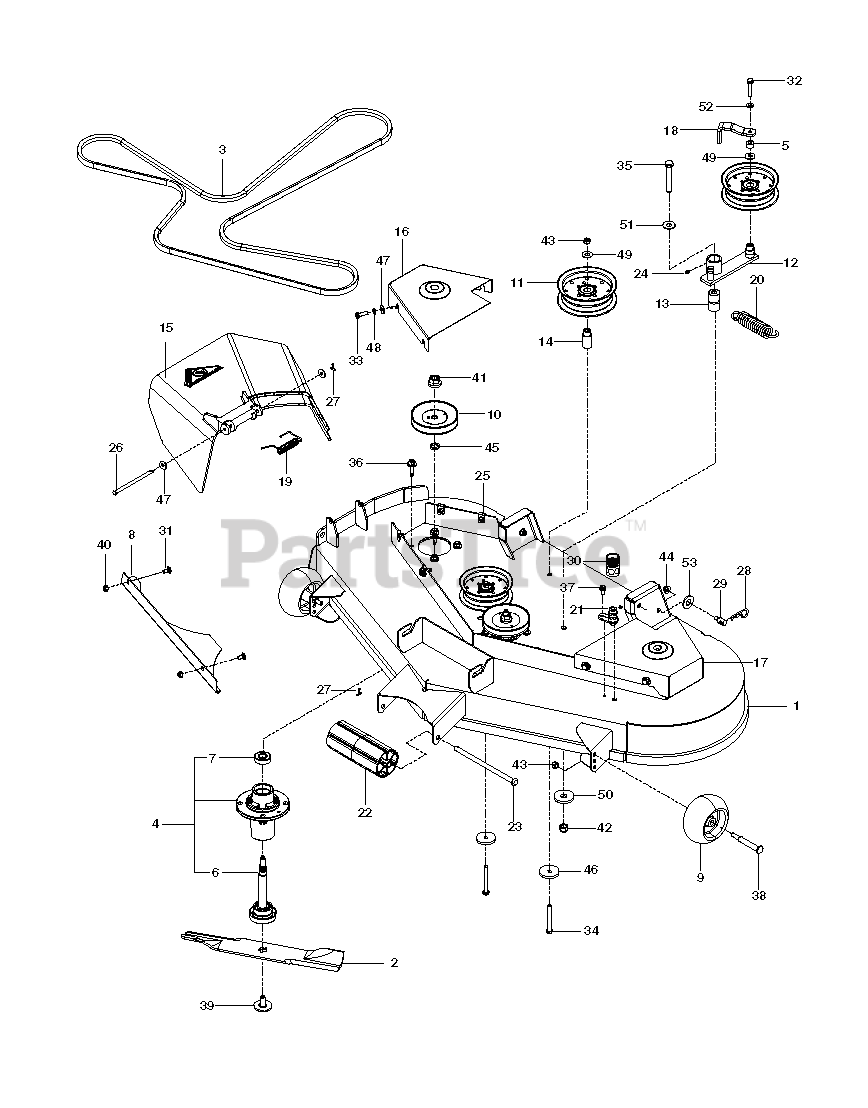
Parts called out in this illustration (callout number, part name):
1	DECK W/DECALS - RAM 48
2	BLADE, 16-1/4" FUSION
4	MANDREL ASM, CAST IRON
6	SHAFT ASM MANDREL
7	BEARING
10	MANDREL PULLEY
11	PULLEY, IDLER
12	IDLER ARM
13	PIVOT BUSHING
14	IDLER BUSHING
15	DISCHARGE CHUTE 48"
16	BELTSHIELD - R.H. BLUE
17	BELTSHIELD - L.H. BLUE
18	GUIDE, BELT
19	SPRING - TORSION
21	PORT.WASHOUT
22	NOSE ROLLER 48"
23	ROD.ROLLER.NOSE.NARROW.48"
24	ZERK
25	U-CLIP 5/16-18 NUT RETAINER
26	PIN-CLEVIS 5/16 DIA X 5.19 ZD
27	COTTER PIN 1/8 X 3/4
28	HAIRPIN #4
29	STUD.FASTNER.W/ANTI-ROTATE
30	COUPLING.QUICK CONNECT
31	CARRIAGE BOLT 5/16C X 5/8"
32	HCS 3/8-16 X 1 3/4 GR5
33	HCS 5/16C X 1
34	HCS 3/8C X 3
35	HCS 1/2C X 3 1/4
37	BOLT 1/4-20 X 1/2 HWST
38	SHOULDER BOLT 1/2X2-5/8 ZD SPE
39	BOLT.WASHER.ASM.7/16-2
40	NUT 5/16 NYLOC
42	NUT 1/2-13 HEX NYLOC ZD
43	NUT 3/8-16 NYLOC
44	5/16-18 NYLOC FLANGE NUT
46	SPINDLE WASHER
47	WASHER 5/16 FLAT
48	WASHER 5/16 LOCK
49	WASHER 3/8 FLAT
50	WASHER, SUPPORT
51	WASHER 1/2 FLAT
52	SLW 3/8 STD
53	WASHER 5/8 FLAT
